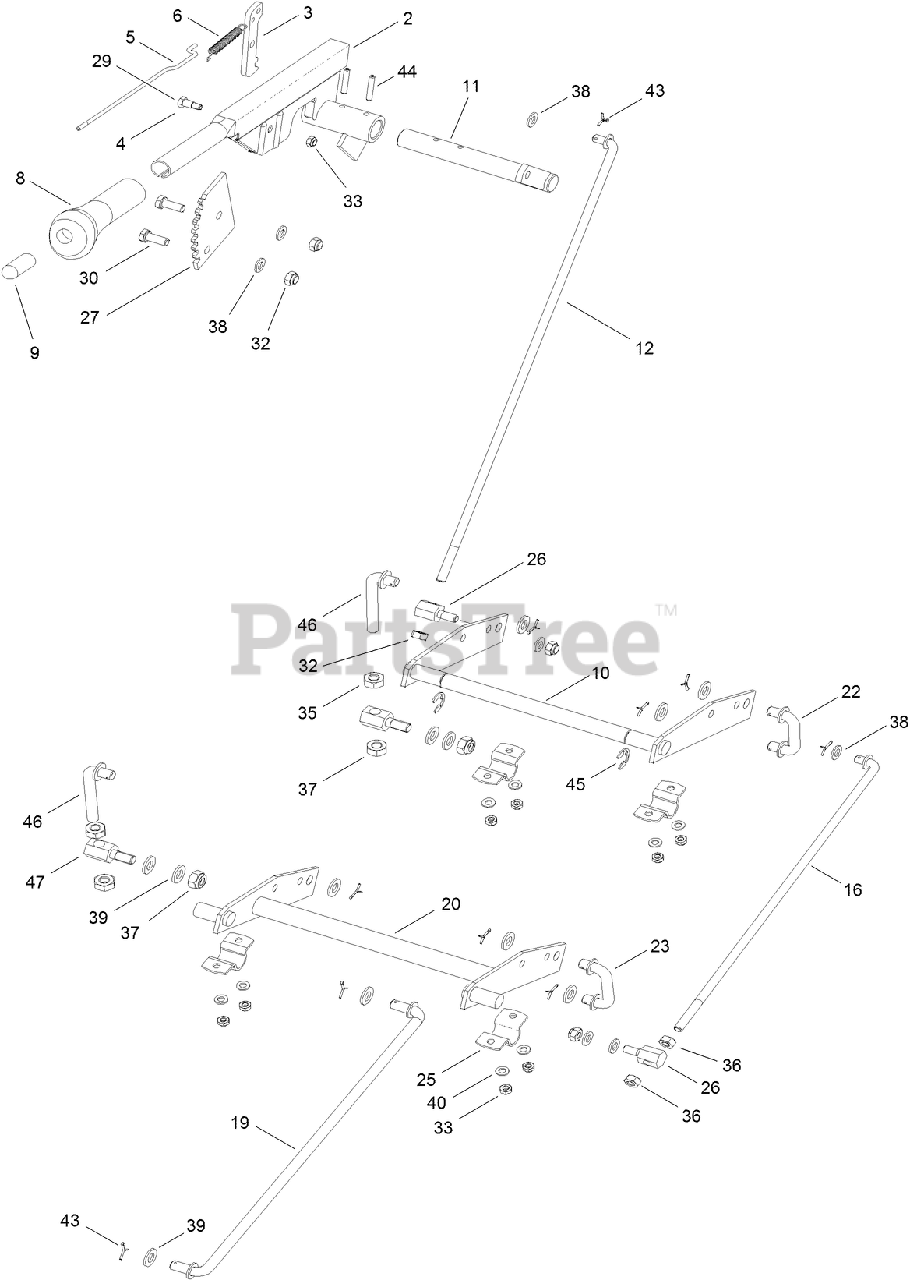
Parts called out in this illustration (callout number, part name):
2	LEVER-ARM
3	RATCHET-PLATE, PIVOT
4	BUSHING
5	ROD-CONNECTION
6	SPRING
8	GRIP-HANDLE
9	BUTTON-PLUNGER
10	HANGER-REAR
11	SHAFT-ADJUSTMENT, HEIGHT
16	ROD-LINKAGE
20	HANGER-FRONT
22	DECK LINK, U-SHAPE, 50
23	DECK LINK, U-SHAPE, 55
26	TRUNNION
27	GEAR-SEGMENT, DECK LIFT
29	SCREW-HH
30	SCREW-HH
32	NUT-LOCK, NI
33	NUT-LOCK
36	NUT-HEX
37	NUT-LOCK, NI
38	WASHER-PLAIN
39	WASHER-FLAT
40	WASHER
43	PIN-COTTER
44	PIN-SPRING
45	E-CLIP
46	LINK-DECK, L-SHAPE (ADJUSTABLE)
47	TRUNION
